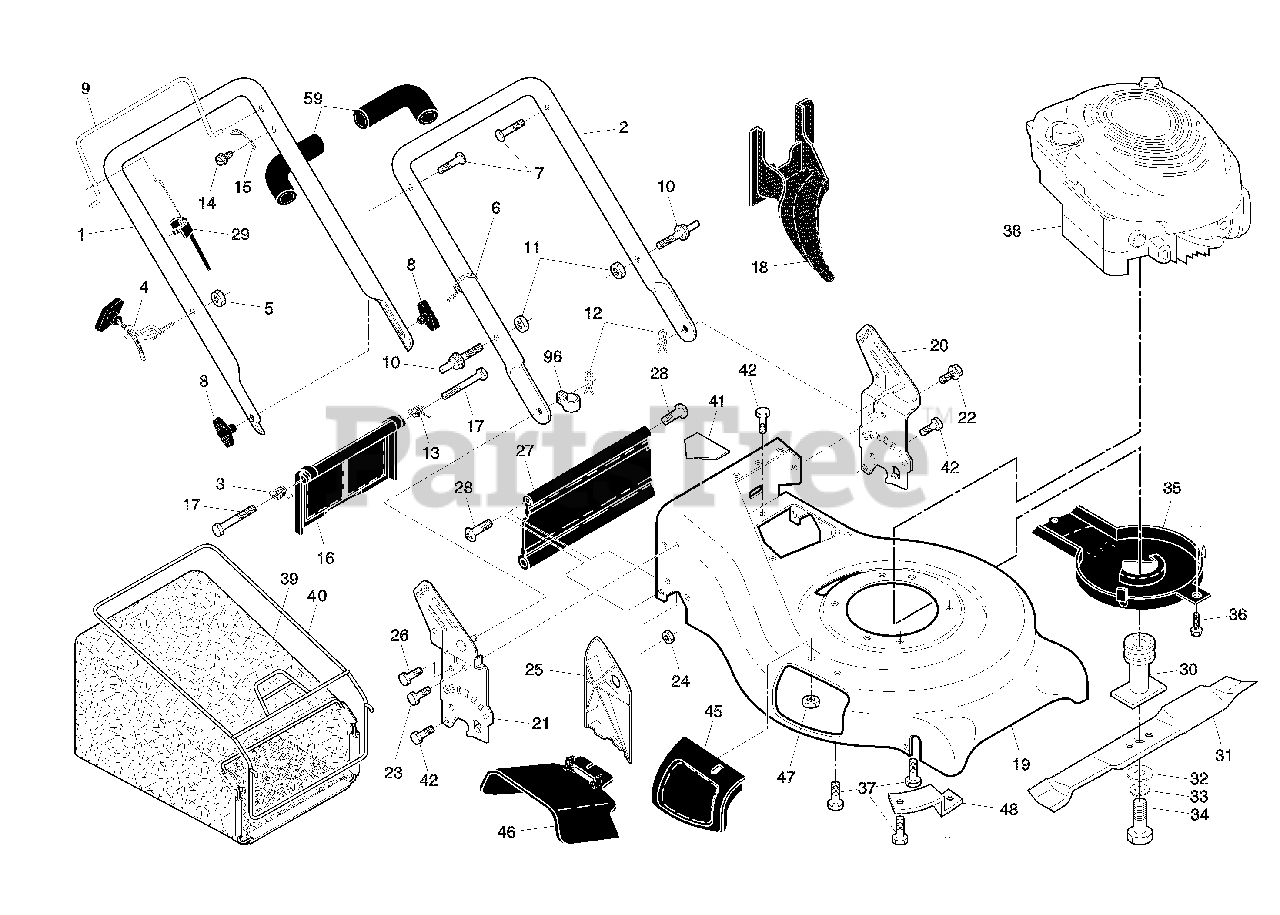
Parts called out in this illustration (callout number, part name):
1	Handle, Upper
2	Handle, Lower
3	Spring, Rear Door, RH
4	Guide, Rope, Side
5	Nut, Hex Lockwasher Insert 1/4-20
6	Wire, Tie
7	Bolt, Handle 5/16-18 x 1.75
8	Knob, Handle
9	Bail, Flat, Auto-Walk, Orange
10	Bolt, Carriage
11	Nut, Hex, Centerlock 5/16-18 UNC
12	Cotter, Hairpin
13	Spring, Rear Door, LH
15	Bracket, Upstop
16	Rear Door Assembly
17	Bolt, Rear Door
18	Plug, Mulcher
19	Kit, Housing
20	Handle Bracket Assembly, LH
21	Handle Bracket Assembly, RH
22	Screw, Hex Washer Head
23	Bolt, Hex Head 5/16-18 x 5/8
24	Nut, Hex, with Lock Washer Insert 5/16-18
25	Baffle, Side
26	Screw, Hi-Lo Thread #12 x 5/8
27	Skirt, Rear
28	Screw, Hinge 1/4-20 x 1.25
29	Cable, Operator Presence
30	Blade Adapter / Pulley
31	Blade, 21"
32	Washer, Hardened
33	Lockwasher, Helical Spring 3/8
34	Screw, Hex Head 3/8-24 x 1.38
35	Debris Shield
37	Bolt, Engine
39	Grassbag
40	Frame, Grassbag
41	Danger Decal
45	Mulcher Door Assembly
46	Defl ector, Discharge
48	Mounting Bracket, Debris Shield
59	Grip, Handle, Foam, Smooth
96	Clip, Cable
